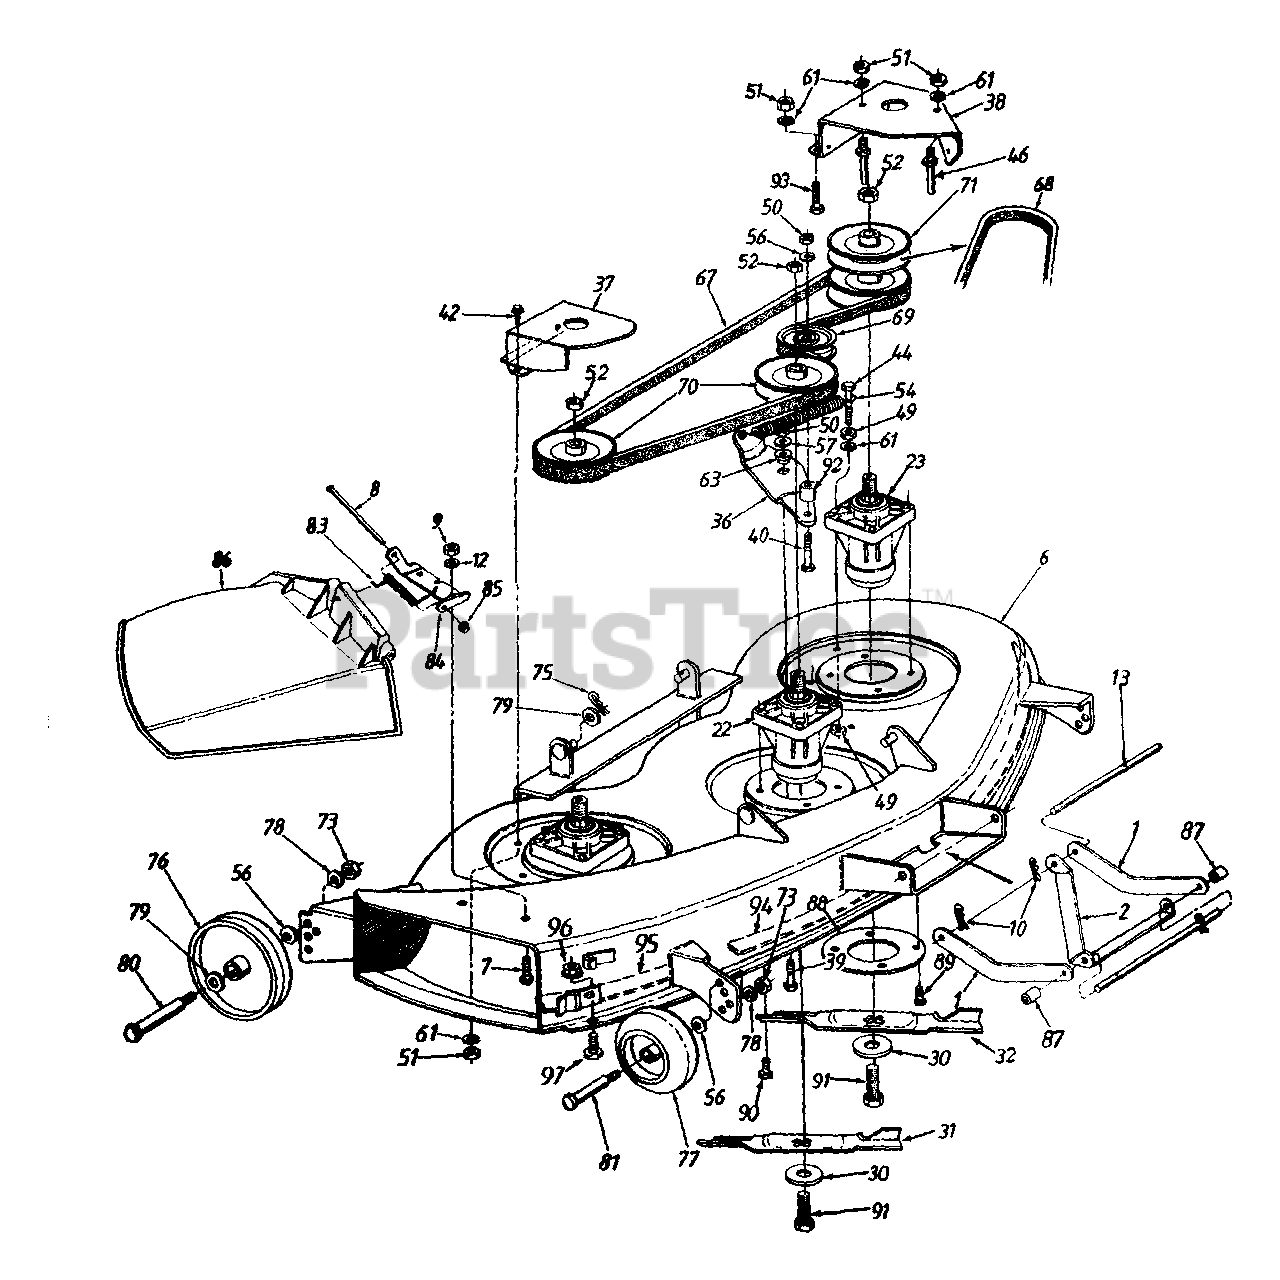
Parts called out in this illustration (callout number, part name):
8	Hinge Pin
9	Hex Nut 1/4-20 Thd.
12	Bell-Wash. 1/4" I.D.
13	Deck Connecting Rod
22	Spindle Ass'y. (R.H. & Center)
23	Spindle Ass'y. (L.H.)
30	Bell-Wash. .47" I.D. x 1.5"
31	High Lift Blade 14.88" Lg. (Middle)
32	High Lift Blade 16.28" Lg. (R.H. & L.H.)
39	Hex Bolt 3/8-24 x 1.0" Lg.
40	Hex Bolt 3/8-24 x 2" Lg.
42	Hex Wash. Hd. Tap-Scr. 1/4-20 x .5" Lg.
44	Hex Bolt 1/4-28 x 1.5" Lg.
46	Belt Guard Pin 1/4" Dia.
49	Hex Nut 1/4-28 Thd.
50	Hex Nut 3/8-24 Thd.
51	Hex Nut 1/4-20 Thd.
52	Hex Flange L-Nut 5/16-18 Thd.
54	Extension Spring 6.17" Lg.
56	Bell-Wash. .38" I.D. x .88" O.D.
57	Bell-Wash. .39" I.D. x 1.13" O.D.
61	L-Wash. 1/4" I.D.
63	Shld. Spacer .625" I.D.
67	V-Belt
68	V-Belt
69	Fl-Idler Pulley 3.5" O.D.
70	Pulley 5.0" Dia.
71	Double Pulley 5.0" Dia.
73	Hex Nut 3/8-16 Thd.
75	Intern. Cotter Pin 3/8 Dia.
76	Deck Wheel 5" Dia.
77	Deck Wheel w/Insert 5" Dia.
78	L-Wash. 3/8" I.D.
79	Fl-Wash. .531" I.D.
80	Shoulder Bolt .498" Dia. x 1.64" Lg.
81	Shoulder Bolt
83	Torsion Spring
84	Hinge Mtg. Brkt.
86	Chute Ass'y. Comp.
87	Spacer 5/8" I.D. x 7/8" O.D.
90	Hex Wash. Hd. Scr. 5/16-18 x .75" Lg.
91	Hex L-Bolt 7/16-20 x 1" Lg.
92	Spacer .38" l.D.
93	Hex Bolt 1/4-20 x .5" Lg.
96	Hex Sems Nut 1/4-20 Thd.
97	Carriage Bolt 1/4-20 x .5" Lg.
